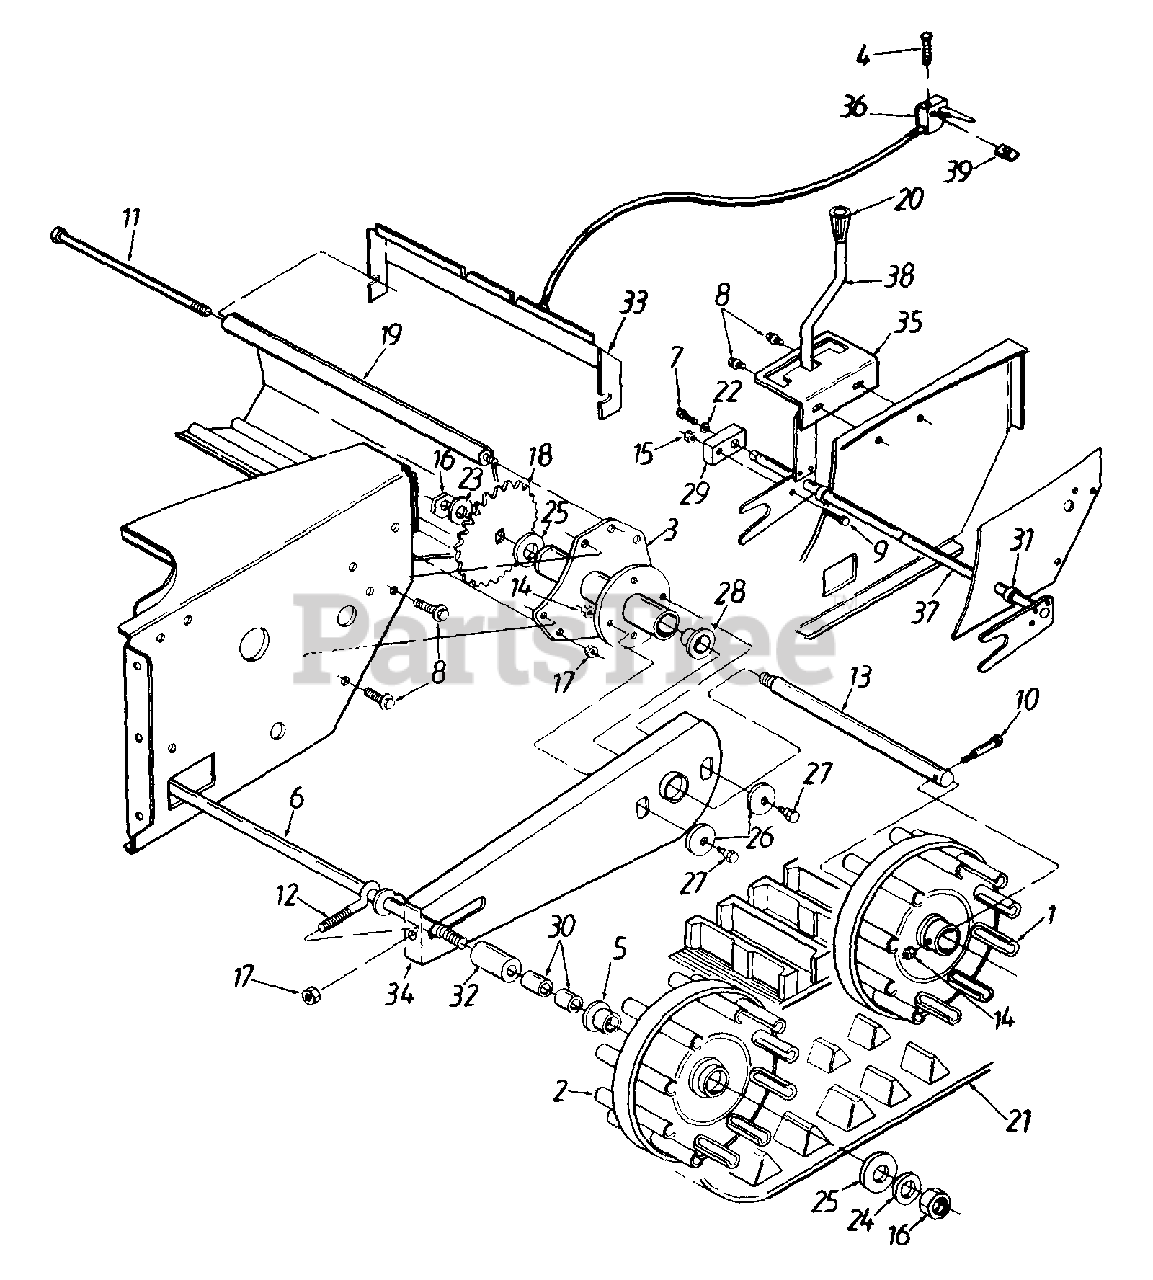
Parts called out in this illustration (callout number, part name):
1	Drive Wheel Ass'y.
2	Idler Wheel Ass'y.
4	Oval C-Sunk Hd. Scr. 10-24 x 1.375" Lg.
5	Flange Bearing 3/4" l.O. x 15/16"
7	Hex Bolt 5/16-24 x .75" Lg.
8	Hex Wash. TT-Tap Scr. 5/16-18 x .62" Lg.
9	Hex Bolt 3/8-24 x 1.5" Lg. (Special)
10	Bolt 5/16-18 x 1.5" Lg.
11	Hex Bolt Ass'y. 5/16-18 x 9.81"
12	Eyebolt 5/16-18 x 3" Lg.
13	Drive Axle
14	Hex Cent. L-Nut 5/16-18 Thd.
15	Hex Cent. L-Nut 3/8-24 Thd.
16	Hex Ins. Jam L-Nut 1/2-20 Thd.
17	Hex L-Nut 5/16-18 Thd.
18	24 Tooth Sprocket
19	Track Housing
21	Snow Track
22	L-Wash. 5/16" I.D.
23	Bell-Wash .515" I D. x 1.14" O.D.
24	Fl-Wash .531" I D. x 1.25" O.D.
25	Fl-Wash .793" I.D. x 1.24" O.D.
26	Fl-Wash. 3/8" I.D x 7/16" O.D.
27	Shld. Bolt .437" Dia. x .162
28	Flange Bearing 3/4" I.D. x 15/16"
29	Lift Shaft Drive
30	Spacer .5" I D x .78" Lg.
31	Spacer .628" I.D. x .5" Lg.
32	Spacer .51" I.D. x 1 34" Lg.
36	Track Steer Cable w/Trigger
39	Flat Weld Nut 010-24 Thd
